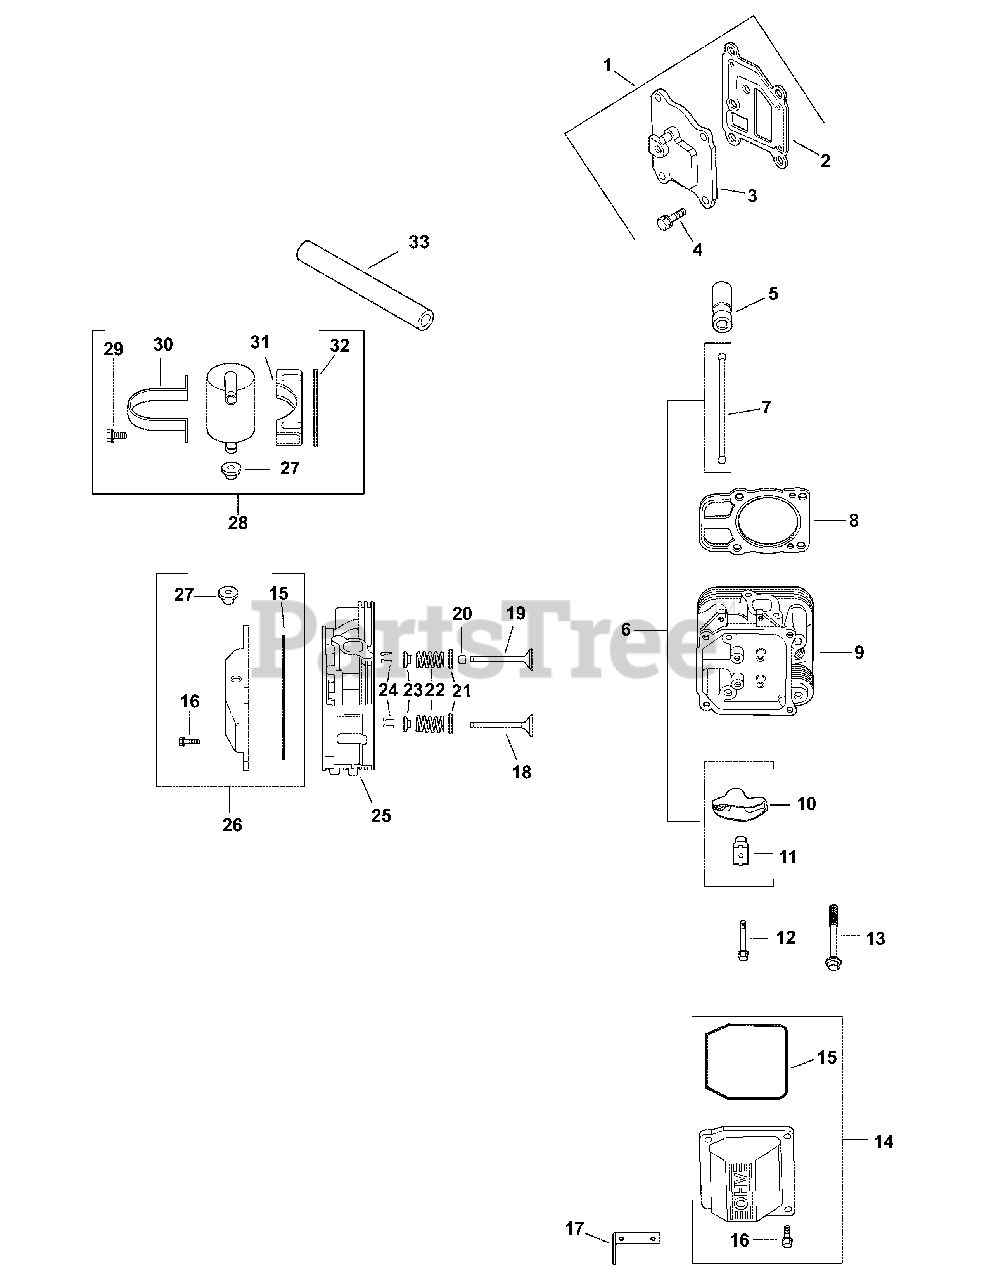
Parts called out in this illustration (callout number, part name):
1	KIT, BREATHER COVER W/GASKET
2	GASKET, BREATHER
3	COVER, BREATHER
4	SCREW, FLG THD FRM M6X1.0X20
5	KIT, HYDRAULIC VAVLE LIFTER
6	KIT, VALVE TRAIN
8	KIT, GASKET CYLINDER HEAD
9	KIT, HEAD #2
11	PIVOT, ROCKER ARM
12	SCREW, FLG M6X1.0X34
13	SCREW, FLG M10X1.5X90
14	KIT, VALVE COVER-PLAIN
15	O-RING, VALVE COVER
16	SCREW, FLG M6X1.0X30
17	STRAP, LIFTING
18	VALVE, EXHAUST (STD)
19	VALVE, INTAKE (STD)
20	SEAL, VALVE STEM
21	RETAINER, SPRING
22	SPRING, VALVE
23	CAP, VALVE SPRING
24	KIT, RETAINER
25	KIT, HEAD #1
26	KIT, VALVE COVER BREATHER
27	GROMMET, RUBBER
28	KIT, BREATHER SEPERATOR
29	SCREW, FLG THD FRM M5X0.8X16
30	STRAP, BREATHER
31	BRACKET, BREATHER SEPERATOR
33	HOSE, BREATHER
